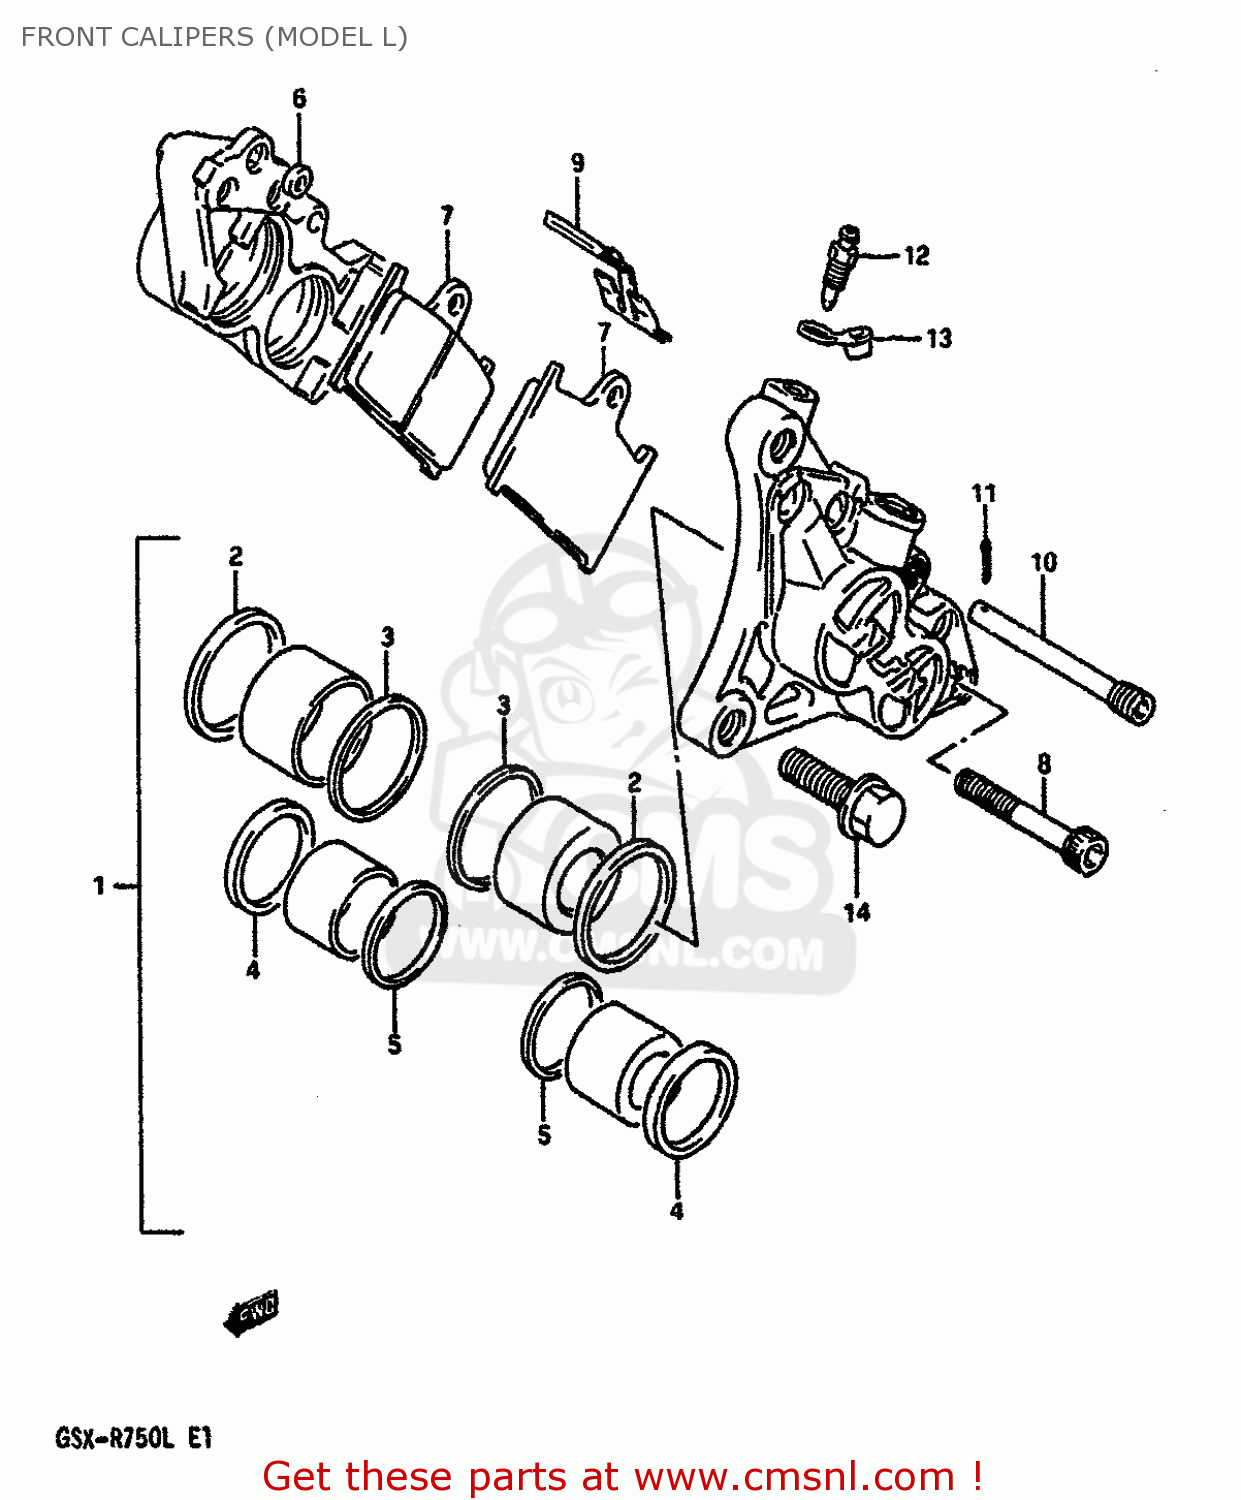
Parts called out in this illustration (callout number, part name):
1	PISTON SET
2	SEAL,PISTON
3	BOOT,PISTON
4	SEAL,PISTON
5	SEAL
6	SEAL
7	PAD,BRAKE
8	BOLT
9	SPRING
10	PIN,HANGER
11	COTTER PIN
12	BLEEDER
13	BLEEDER
14	BOLT 10X30
15	BOLT
16	BOLT 10X30
